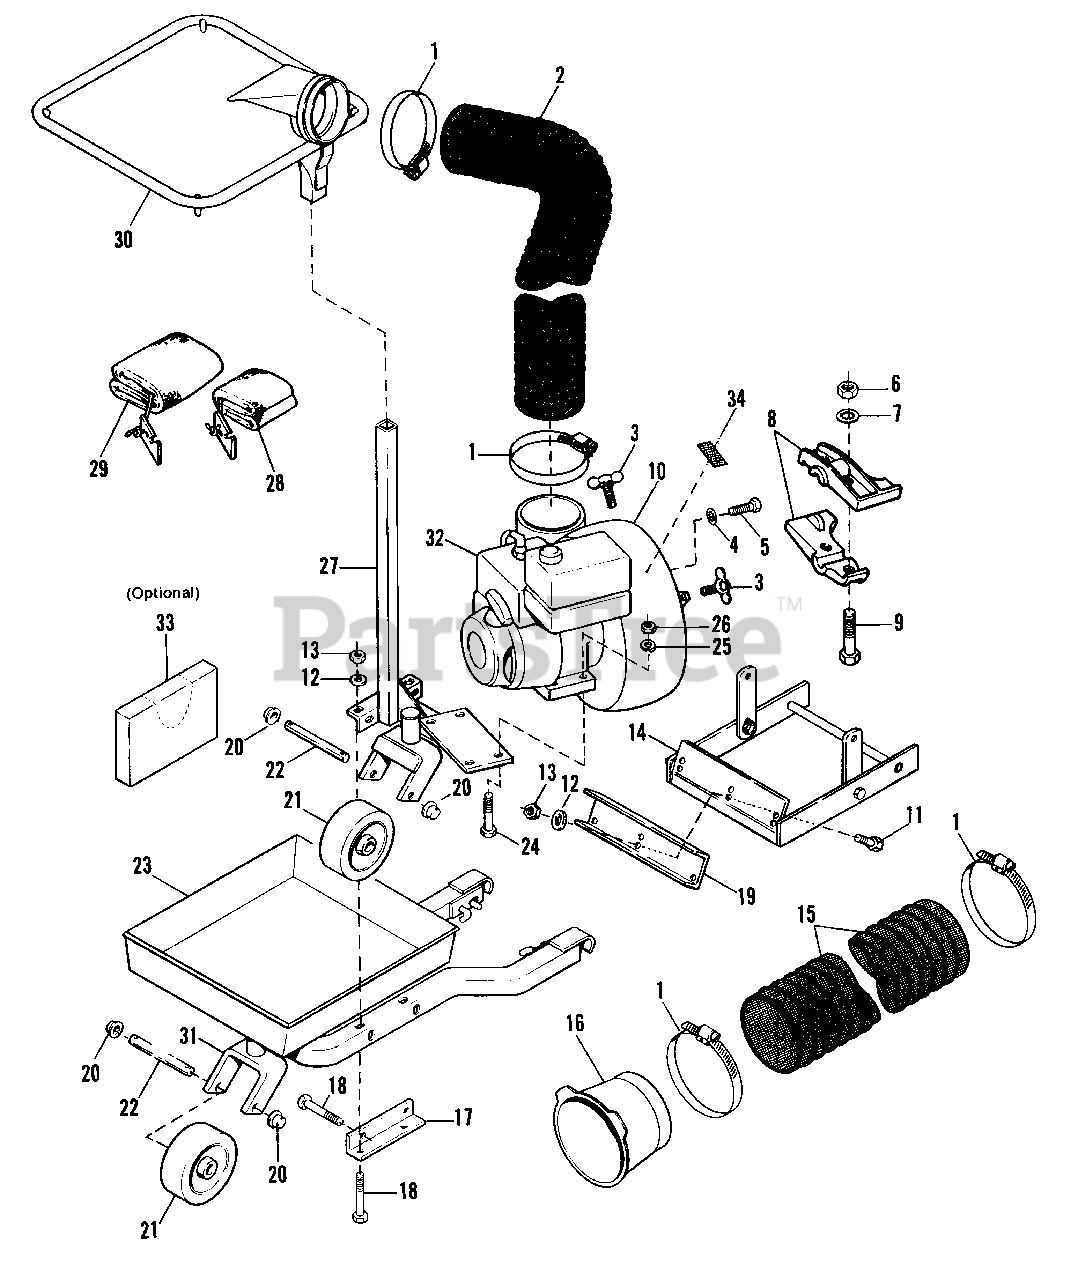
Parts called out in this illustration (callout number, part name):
1	CLAMP, Hose
2	HOSE, Flexible
3	BOLT, Wings, 5/16-18 x 2
4	LOCKWASHER, Int., 5/16
5	CAPSCREW, Hex, Hd.,5/16-24 x 3/4
6	NUT, Hex, Fu11, 1/2-13
7	LOCKWASHER, Int., 1/2
8	BLADES, Blower (Pair)
9	CAPSCREW, Hex Hd., 1/2-13 x 1-1/2
10	HOUSING, Blower
11	CAPSCREW, Hex Hd., 3/8-16 x 1
12	LOCKWASHER, 3/8
13	NUT, Hex, Full 3/8-16
14	HITCH ASSY.
15	HOSE, Lower
17	ANGLE, Reinforcing
18	CAPSCREW, Hex Hd., 3/8-16 x 2-1/2
19	CLAMP, Mount
21	WHEEL, Caster
22	AXLE, Caster
23	TRAY & SUPPORT ASSY.
24	CAPSCREW, Hex Hd., 5/16-18 x 1-1/2
25	LOCKWASHER, 5/16
26	NUT, Hex, Full, 5/16-18
27	ENGINE MOUNT & UPRIGHT
28	TOP, Canvas Bag
29	BAG, Canvas
30	RING, Bag Support
31	FORK ASSY., Caster
32	ENGINE, 4 H.P., Briggs & Stratton
33	LINERS, Plastic Bag (pkg of 18)
34	DECAL, Warning
